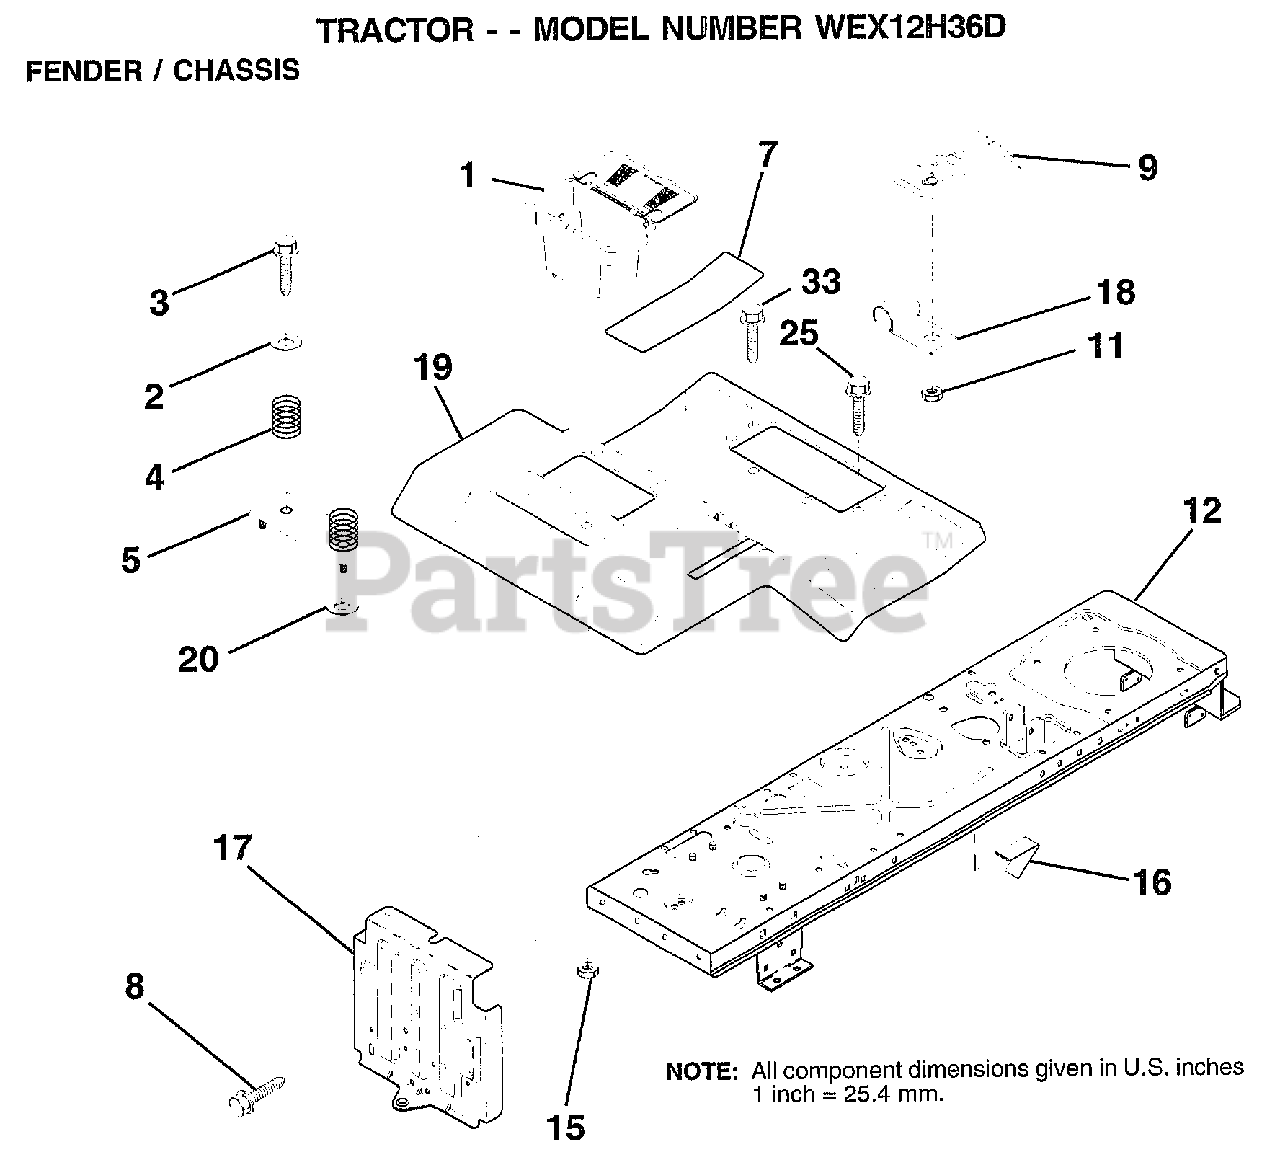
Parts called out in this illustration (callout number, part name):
1	"CASE,BATTERY.MECH"
2	WASHER
3	SCREW
4	SPRING COMPRESSIO
5	PLATE.FEND.LR.ASM
7	PAD FOOTREST
8	SCREW
9	CONSOLE.SHIFT CONTROL
11	NUT
12	CHASSIS.WELD.ASM.
15	NUT HXKEP 1/4X20
17	DRAWBAR ASM LR
18	"CLIP,INSULATOR"
19	FENDER/FOOTREST
25	SCREW TAPPING
33	SCREW
